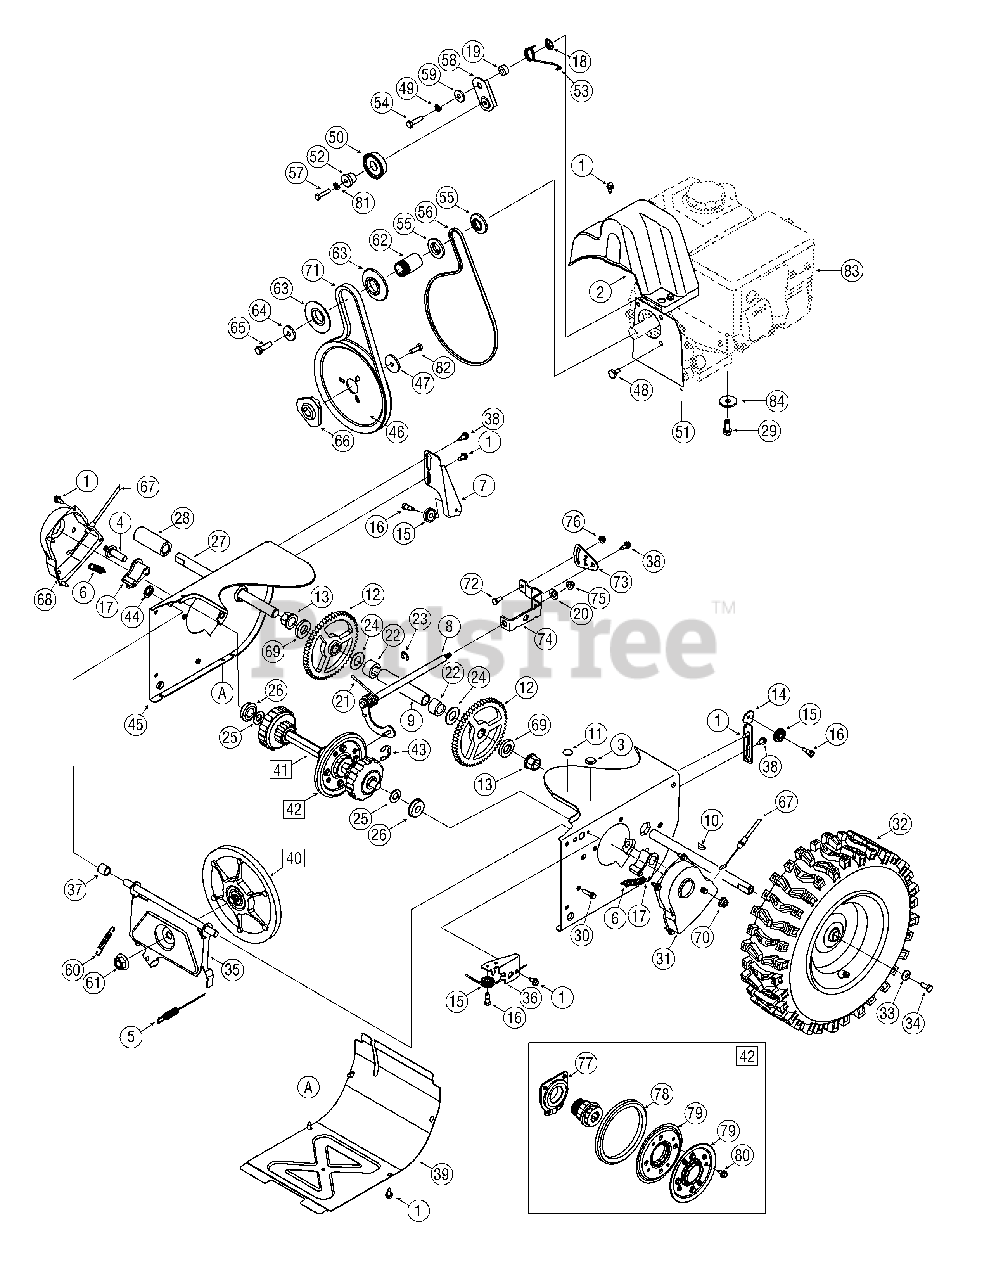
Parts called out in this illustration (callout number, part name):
1	AB Screw, 1/4-20 x 0.625
2	Belt Cover
3	Plug, 3/8 ID
4	Actuator Shaft
5	Drive Clutch Cable
6	Extension Spring
7	Drive Clutch Cable Guide Bracket
8	Shift Rod Assembly
9	Axle Support Tube
10	Hi Pro Key
11	Plug, 1/2 ID
12	Gear, 56T
13	Hex Flange Bearing
14	Auger Clutch Cable Guide Bracket
15	Cable Roller
16	C Screw, 1/4-28 x 0.375
17	Dogg Assembly - LH
17	Dogg Assembly - RH
18	Push-on Nut
20	Washer, Flat
21	Torsion Spring, .750 ID x .968 Lg.
22	Spacer
23	E Ring
24	Flat Washer, .76 x 1.49 x .06
25	Flat Washer
26	Ball Bearing
28	Spacer
29	TT Sems Screw, 3/8-16 x 1.0
30	TT Screw, 1/4-20 x 1.0
31	Shaft Retainer - LH
32	Wheel Complete - LH
32	Wheel Complete - RH
33	Bell Washer
34	Hex Bolt, 5/16-24 x 0.75
35	Friction Wheel Support Brkt. Assy.
36	Auger Cable Guide Bracket
37	Spacer
38	Shoulder Screw
39	Frame Cover
40	Friction Wheel Disc Assembly
41	Drive Shaft Assembly
42	Friction Wheel Assembly
43	Retainer Ring
44	Speed Nut
45	Wheel Drive Frame
46	Auger Pulley
47	Flat Washer
48	Shoulder Screw
49	Lock Washer
50	Idler Pulley Assembly
51	Plt., Cvr.
52	Spacer
53	Torsion Spring
54	Hex Screw, 5/16-24 x 1.25
55	Pulley Half
56	Belt, Wheel Drive
57	TT Screw, 1/4-20 x 1.25
58	Drive Clutch Idler Bracket
59	Shoulder Spacer
60	Extension Spring
61	Flange Nut, 5/8-18
62	Spacer
63	Pulley Half
64	Flat Washer
65	Hex Bolt, 3/8-24 x 1.25
66	Pulley Adapter
67	Steering Cable
68	Shaft Retainer - RH
69	Axle Spacer
70	Flange Lock Nut, 3/8-16
71	V-Belt,.500 x 37.00 Lg
72	Hex Screw, 1/4-20 x .620
73	Speed Selector Pivot Bracket
74	Speed Selector Shift Bracket
75	Flange Lock Nut, 5/16-18
76	Flange Lock Nut, 1/4-20
77	Friction Wheel Bearing Assembly
78	Friction Wheel
79	Friction Plate
80	Screw, 1/4-20 x .500
81	Lock Washer
82	Hex Bolt, 5/16-24 x 0.875
83	Replacement Engine
84	Wash., Flat, .380 x 1.380 x .125
